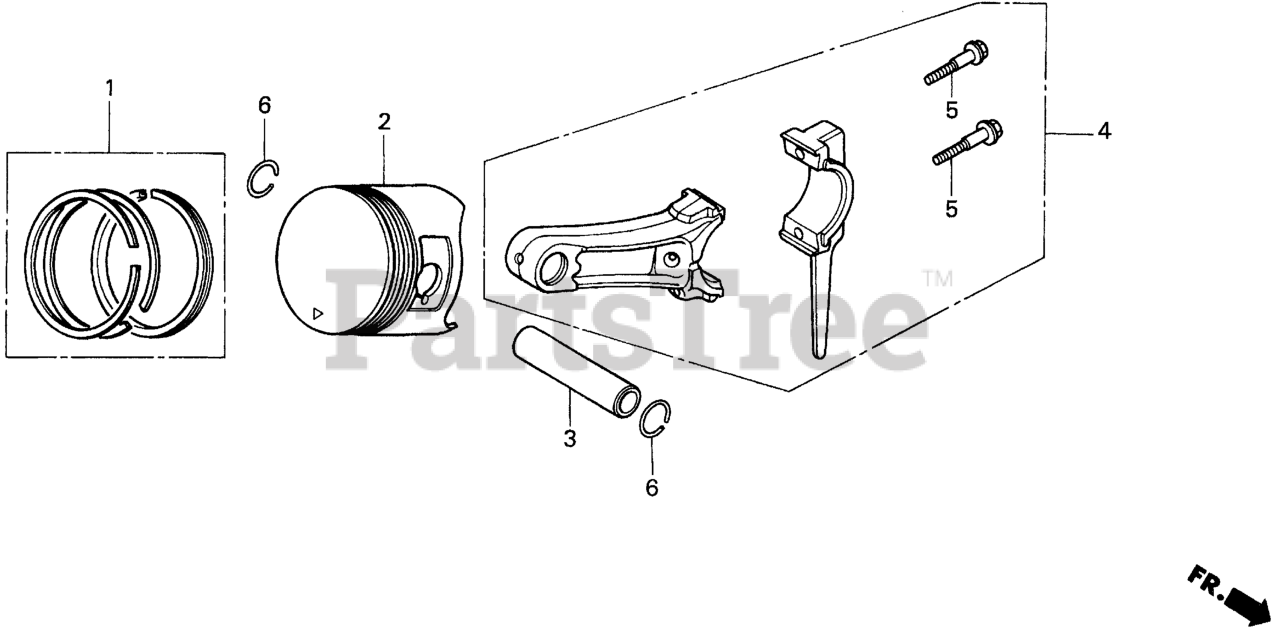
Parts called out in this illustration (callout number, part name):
1	RING SET, PISTON (STD) (NIPPON)
1	RING SET, PISTON (OVER SIZE) (0.25) (NIPPON) Use up to Engine SN 3993725.
1	RING SET, PISTON (OVER SIZE) (0.50) (NIPPON) Use up to Engine SN 3993725.
1	RING SET, PISTON (0.50) (TEIKOKU)
1	RING SET, PISTON (OVER SIZE) (0.75) (NIPPON) Use up to Engine SN 3993725.
1	RING SET, PISTON (0.75) Use up to Engine SN 3993725.
2	PISTON (OS 0.25) Use up to Engine SN 3993725.
2	PISTON (OVER SIZE) (0.50) Use up to Engine SN 3993725.
2	PISTON (0.75)
2	PISTON (STD)
3	PIN, PISTON
4	ROD ASSY., CONNECTING (UNDER SIZE)
4	ROD ASSY., CONNECTING
4	CONN ROD ASSY.
5	BOLT, CONNECTING ROD
6	CLIP, PISTON PIN (13MM)
